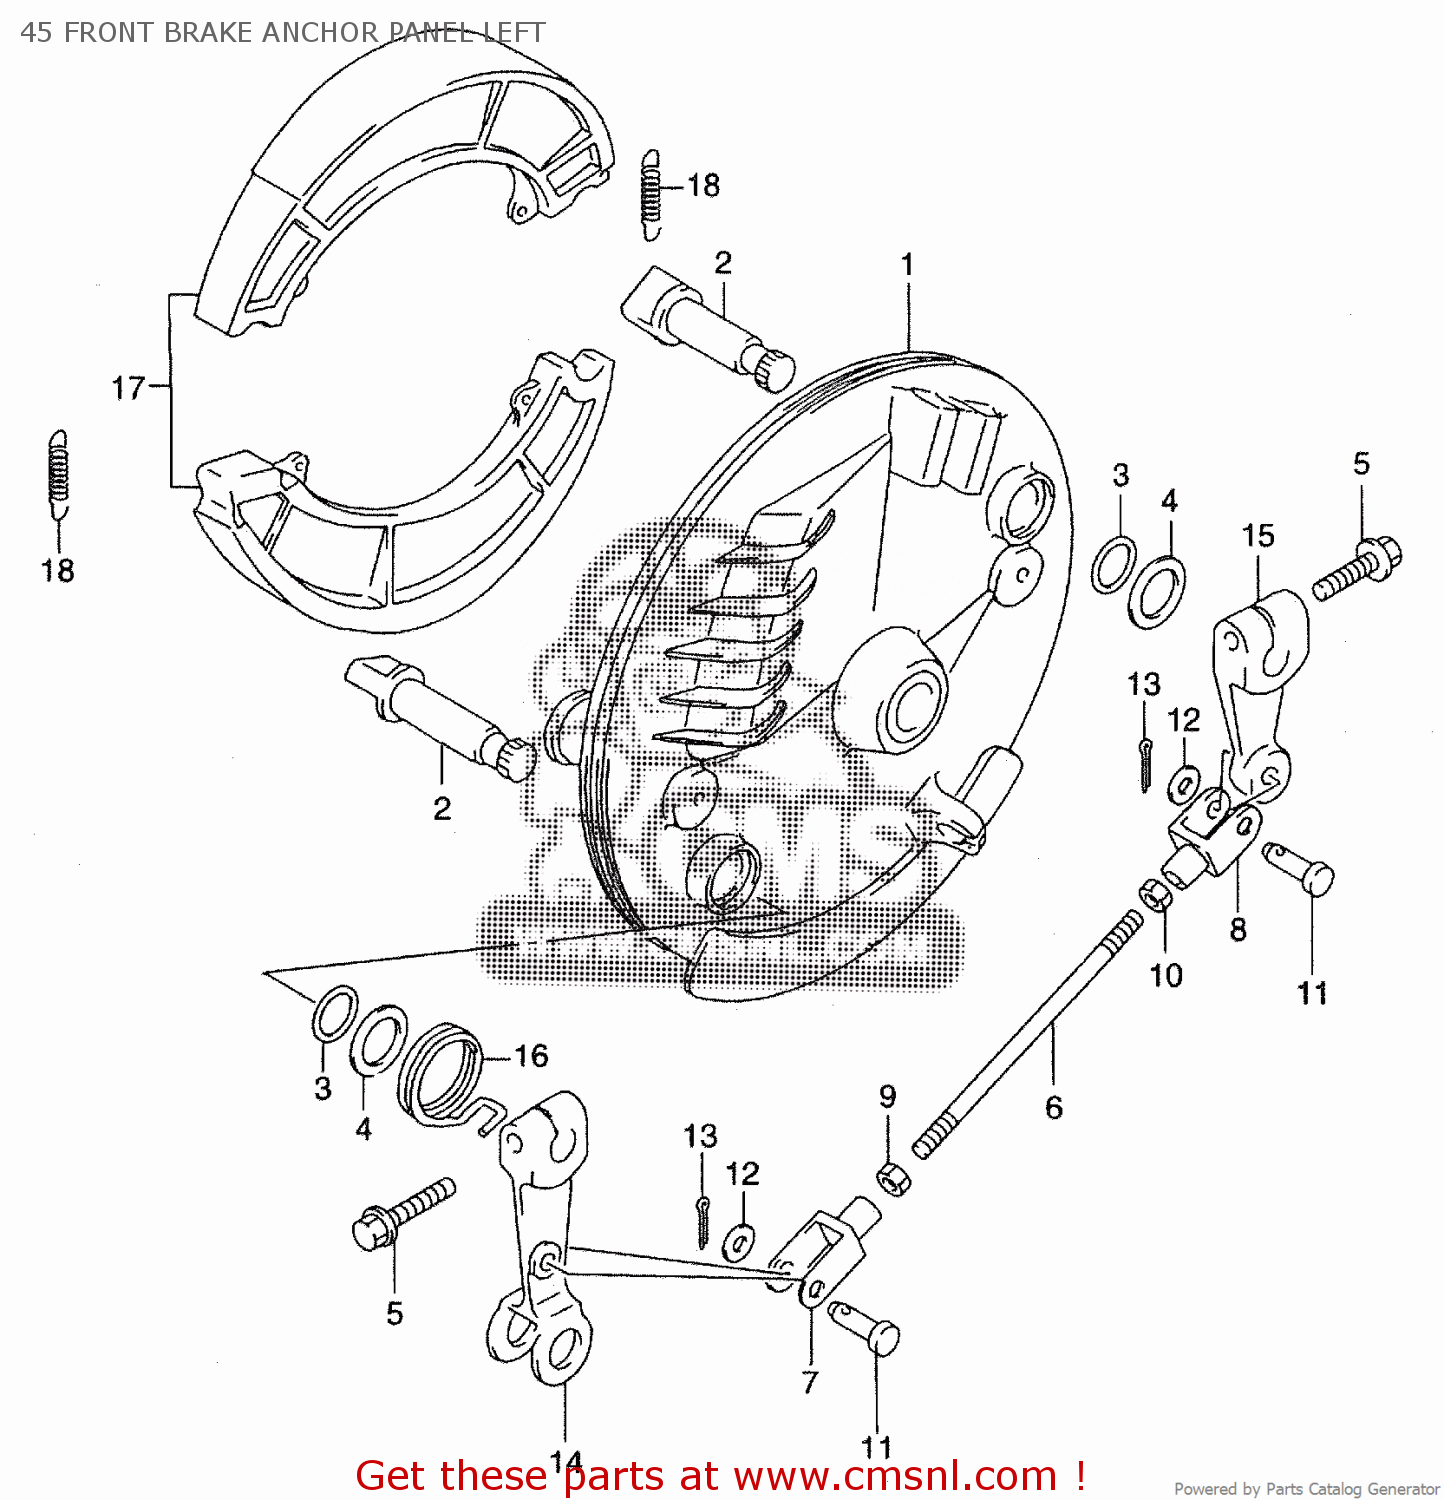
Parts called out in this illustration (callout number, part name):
1	PANEL, FRONT BRAKE ANCHOR
2	CAM, FRONT BRAKE L/H
3	O RING(D:2.4,ID:14.8)
4	WASHER(15.5X24X1.6)
5	BOLT
6	CONNECTING ROD,BRAKE CAM LEVER
7	END,CAM LEVER CONNROD FR
8	END,CAM LEVER CONNROD RR
9	NUT
10	NUT
11	PIN
12	WASHER
13	PIN
14	LEVER,FR BRAKE CAM NO.1
15	LEVER,FR BRAKE CAM NO.2
16	SPRING, CAM LEVER RETURN L/H
17	SHOE SET,FR BRAKE (NAS)
18	SPRING,BRAKE SHOE
